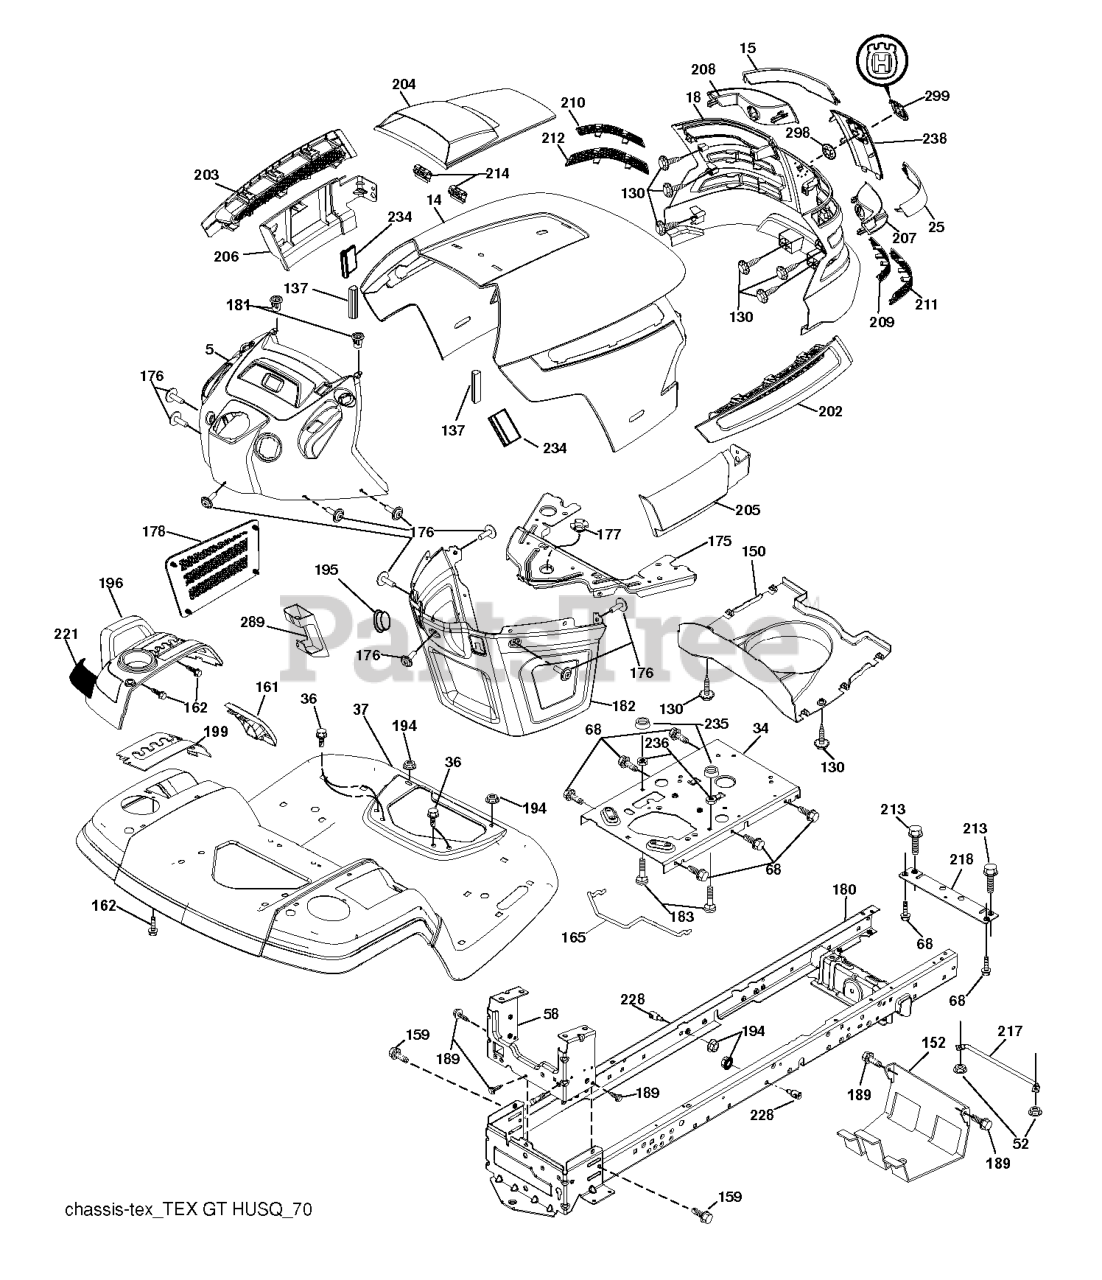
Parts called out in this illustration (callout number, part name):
14	HOOD
15	LENS.LH.TEX.GT.HUSQ.CL
18	GRILL.ASM.HUSQ.TG/CRD.W/TRIM
25	LENS.RH.TEX.GT.HUSQ.CL
34	PLATE.ENGINE.WELDED.CHASSIS
36	SCREW 5/16"
37	FENDER.PNT.TX.GT.CH/FW.ORANGE
52	LOCKNUT
58	DRAWBAR.UPPER.2PC,LRG.FENDER
68	Screw 5/16-18 x 1/2 Hex, Self Tapping 5/16-18 x 1/2
130	SCREW.#10 X 0.750.BOS
137	BUMPER DASH
150	AIR.DUCT.TEXGT.HUSQ.31
152	SHIELD.BROWNING.W/TEX
159	SCREW, 3/8-16X3/4
161	CONSOLE.FUEL.WINDOW.HU
162	SCREW.HI-LO.CONSOLE
165	SUPPORT.TANK.REAR.W/TEX
175	PLATE.CROSSMEMBER.HUSQ
176	SCREW.#10-24X5/8.RN.QU
177	BUSHING, STEERING
178	CARGO.ASM.NET.TXGT.W/C
180	CHASS.WLDMNT.TLT.12GA/2PC.20"
181	BUSHING.MNT.FEND.CRGO.
182	DASH.LOWER.COMMON.12V.ADAPTOR
183	BOLT.5/16-18X1-1/4 FULL.THREAD
189	SCREW
194	NUT LOCK HEX FLANGE 5/16-18
195	PLUG.HOLE.DASH.LOWER.12V.BLK
196	RP CONSOLE.ASM.DECKLFT.W/
199	PLATE.DECK.LIFT.HUSQVARNA.GT
202	VENT.SIDE.HOOD.HUSQ.RH.GREY
203	VENT.SIDE.HOOD.HUSQ.LH.GRAY
204	HOOD VENT
205	SKIRT.HOOD.SIDE.HUSQ.RH.GREY
206	SKIRT.HOOD.SIDE.HUSQ.LH.GREY
207	BEZEL.RH.TEX.GT.HUSQ
208	BEZEL.LH.TEX.GT.HUSQ
209	INSERT.HEX.GRILL.HUSQ.GREY
210	INSERT.HEX.GRILL.HUSQ.
211	INSERT.HEX.GRILL.HUSQ.
212	INSERT.HEX.GRILL.HUSQ.
213	BOLT
214	CLIP.RETAINER.TINNER.
217	ROD.PIVOT.HOOD
218	X-PIECE.HOOD.STOP.NON/
221	REFLECTOR.LH.TEX GT HU
228	STUD.FASTNER.W/ANTI-ROTATE
234	BUMPER.HOOD.TEX.HUSQVARNA
235	SPACER FENDER
236	NUT.CENTERLOCK.5/16-
238	TRIM.HUSQ.TG/CRD.SERVICE
289	PLUG.N/CRUISE.COMMON.YT/GT.BLK
298	NUT PUSH M
299	RP LOGO
